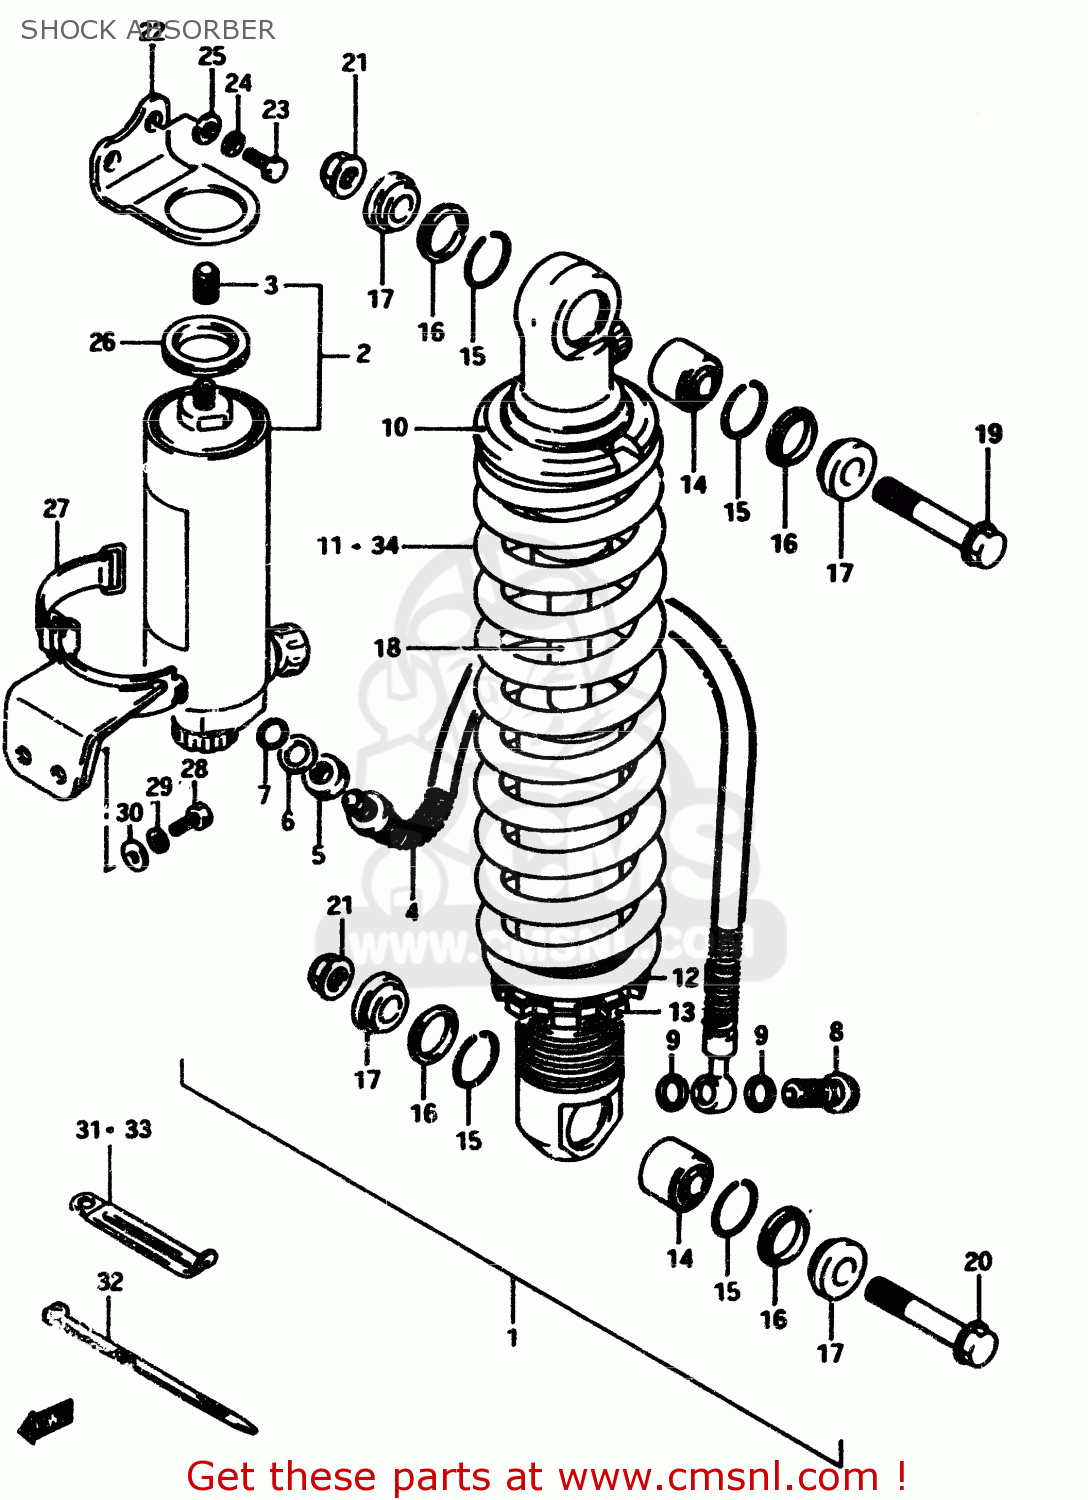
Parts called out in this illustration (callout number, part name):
1	SHOCK ABSORBER, REAR (BLUE)
2	TANK
3	CAP
4	HOSE,REAR SHOCK ABSORBER
5	NUT 12MM
6	WASHER,REAR SHOCK HOSE
7	O-RING,RESERVE TANK
8	BOLT,REAR SHOCK ABSORBER
9	GASKET (NAS)
10	GUIDE,REAR SHOCK ABSORBER SPRING
11	SPRING
12	GUIDE,SPRING
13	GUIDE,REAR SHOCK ABSORBER SPRING
14	BEARING,REAR SHOCK ABSORBER
15	RING
16	SEAL,DUST RR SHOCK ABSORBER
17	COLLAR
18	PISTON ROD
19	BOLT,REAR SHOCK ABSORBER
20	BOLT(10X58)
21	NUT
22	BRACKET,RESERVOIR TANK
23	BOLT
24	WASHER,LOCK
25	WASHER
26	CUSHION,RESERVOIR TANK
27	BRACKET,RESERVOIR TANK
28	BOLT, UPPER
29	WASHER,LOCK
30	WASHER
31	CLAMP
32	CLAMP
33	CLAMP
34	SPRING (SOFT)
